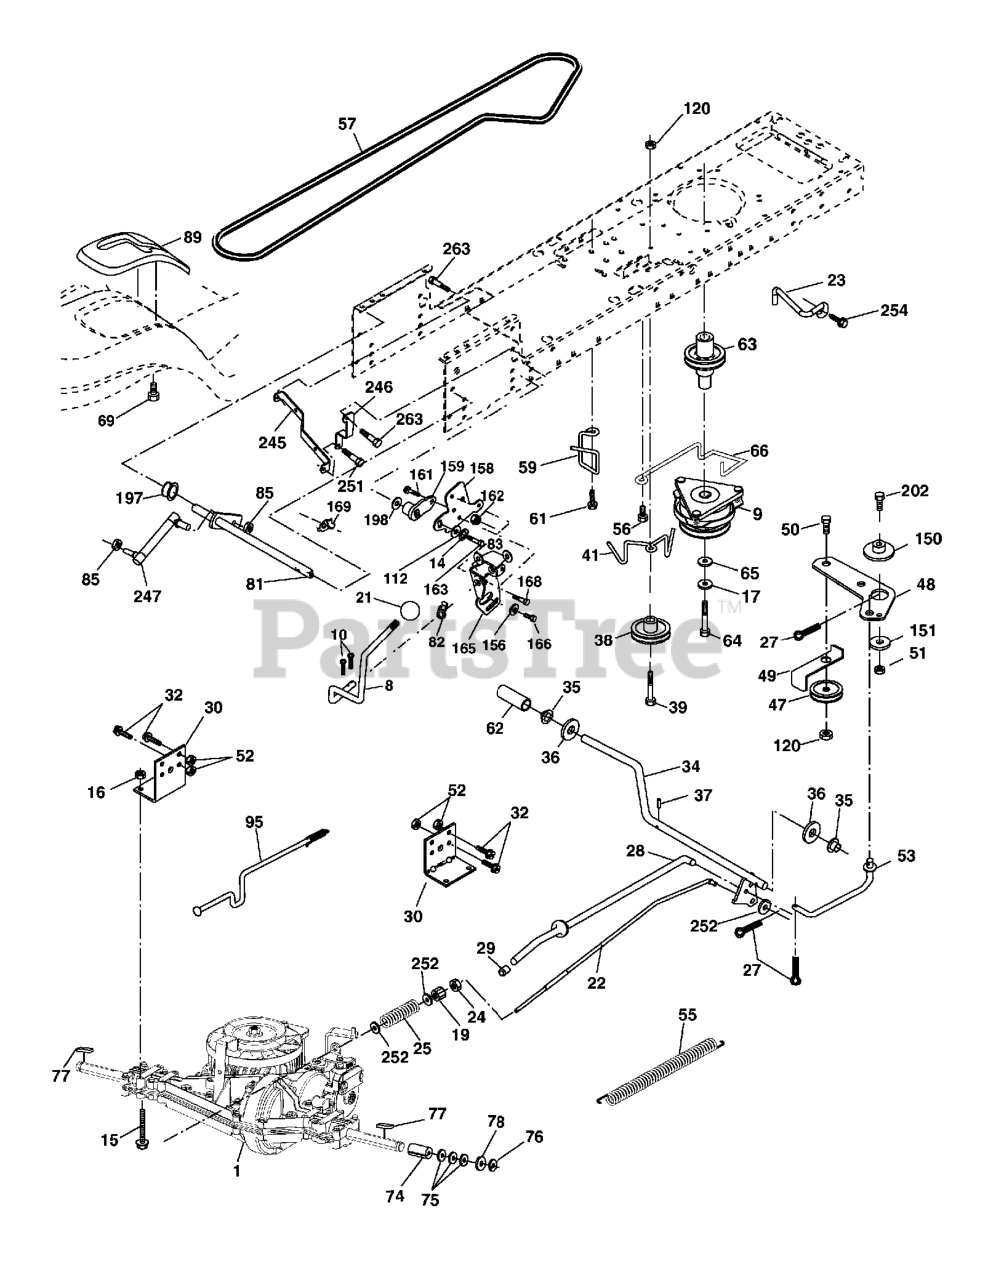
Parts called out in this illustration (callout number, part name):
8	ROD.SHIFT.FENDER.ADJ.STLT
9	CLUTCH ELECTRIC
10	PIN COTTER
14	LOCKWASHER
15	BOLT HEX 5/16-18 GR 5
16	NUT.71038.31-18.HEX.NYLOCK
17	WASHER
19	NUT
21	KNOB.DELUXE.(PISTOL.GRIP).BLAC
22	ROD.BRAKE
23	BRACKET, ANTI-ROTATION
24	NUT
25	SPRING ROD LT
27	COTTER PIN
28	ROD, PARKING BRAKE
29	PLUNGER CAP
30	BRKT, TRNSXLE MNT 20"
32	BOLT
34	SHAFT, FOOT PEDAL
35	BEARING.NYLON
36	WASHER LT
37	DRIVE PIN
38	PULLEY IDLER COMPOSITE
39	BOLT
41	KEEPER, BELT IDLER
47	IDLER PULLEY
48	BELLCRANK, CLUTCH
49	RETAIN BELT
50	BOLT.3/8-16X1.50
51	LOCKNUT
52	LOCKNUT
53	LINK, CLUTCH LT
55	SPRING, RETURN LT
56	SCREW.3/8-16
57	V-BELT DRIVE
59	KEEPER, BELT CENTER
61	SCREW 3/8-16X.875
62	PEDAL COVER T
63	PULLEY- ENGINE
64	BOLT HEX 7/16-20X4-1/4"
65	LOCKWASHER
66	KEEPER BELT ENGINE
69	SCREW.HI-LO.CONSOLE
74	SPACER AXLE
75	WASHER
76	E-RING LT
77	SQUARE KEY
78	WASHER
81	SHAFT ASM
82	SHIFT SPRING
83	WASHER
85	NUT LOCK CENTER 1/4 -28 FNTHD
89	CONSOLE, SHIFT, STL, AUTO GREY
95	DISCONNECT.ASM.ROD.BYPASS
112	WASHER LT
120	NUT LOCK FLG 3/8-16 UNC
150	SPACER, RETAINER
151	WASHER 12/32X2X10GA
156	WASHER.SRRTD.5/16
158	BRACKET
159	RB HUB.SHIFT
161	BOLT
162	NUT.CROWNLOCK.1/4
163	BOLT
165	RP BRACKET
166	CAPSCREW.HXHD.FLG.5/16-18X.625
168	BOLT.SHOULDER.5/16-18X
169	PLATE.FASTENING.CROSS.SHAFT
197	NYLINER SNAP 5/8" ID
198	WASHER.NYL.7/8IDX.105"HYD CR
202	BOLT
245	STRAP, TORQUE
246	STRAP, TORQUE
247	LINK
251	SCREW 5/16-18X1
252	WASHER
254	SCREW 3/8-16X1
263	SCREW, 3/8-16X3/4
